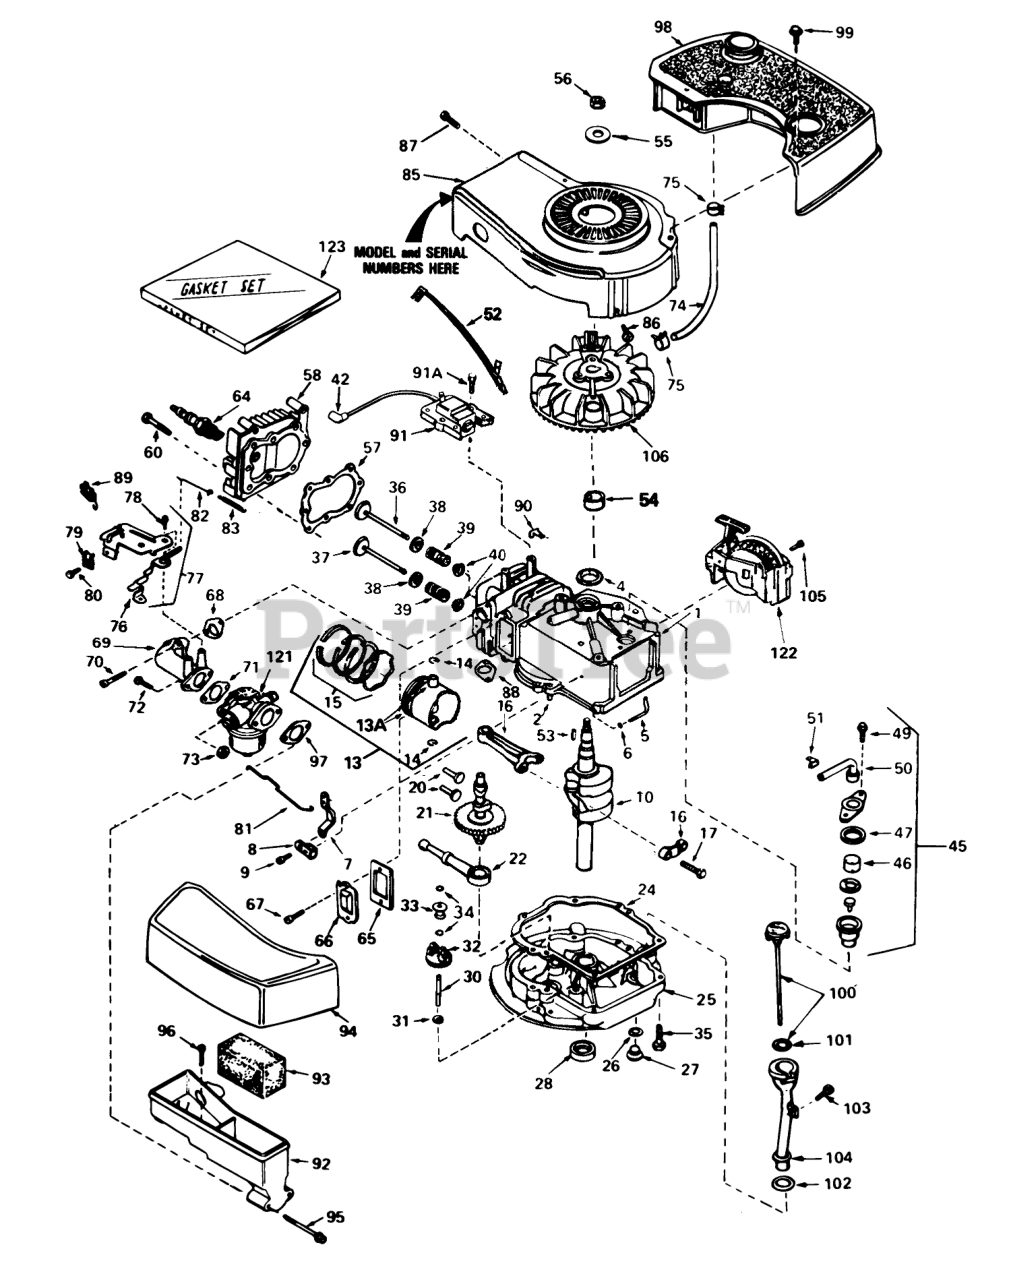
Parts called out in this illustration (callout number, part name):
1	Cylinder Assy. (Incl. #2 & 4)
2	Pin-Dowel
4	Seal-Oil
5	Rod, Governor (Incl. #6)
6	Washer-Flat
7	Governor Lever
8	Clamp-Lever, Governor
9	Screw
10	Crankshaft
13	Piston, Pin & Ring Assy. (Std.) (Incl. #13A, 14 & 15)
13	Piston, Pin & Ring Assy. (.010 oversize) (Incl. #13A, 14 & 15)
13	Piston, Pin & Ring Assy. (.020 oversize) (Incl. #13A, 14 & 15)
13A	Piston & Pin Assy. (Std.) (Incl. #14)
13A	Piston & Pin Assy. (.010 oversize) (Incl. #14)
13A	Piston & Pin Assy. (.020 oversize) (Incl. #14)
14	Ring-Retaining, Piston Pin
15	Ring Set (Std.)
15	Ring Set (.020" OS)
15	Ring Set (.010" OS)
16	Rod Assy., Connecting (Incl. #17)
17	Bolt-Rod, Connecting
20	Lifter-Valve
21	Camshaft(Mech.Comp. Release)
22	Oil Pump ASM
24	Gasket, Mounting
25	Flange Assy., Mounting (Incl. #26 thru 30)
26	Gasket-Oil Drain
27	Plug Oil Drain
28	Seal Oil
30	Shaft-Governor
31	Washer-Flat
32	Gear Assy., Governor (Incl. #31)
33	Spool-Governor
34	Ring-Retaining
35	Screw (1/4-20 x 1-1/4)
36	Valve, Intake (Std.) (Incl. #40)
36	Valve, Intake (1/32" oversize) (Incl. #40)
37	Valve, Exhaust (Std.) (Incl. #40)
37	Valve, Exhaust (1/32" oversize) (Incl. #40)
38	Cap-Upper Valve Spring
39	Spring-Valve
40	Cap-Valve, Spring
42	Cover-Spark Plug
45	Breather Assy. (Incl. #46 thru 51)
46	Element-Breather
47	Gasket-Breather
49	Screw (10-24 x 9/16)
50	Tube, Breaker
51	Clip, Breather
52	Wire-Ground
53	Key-Flywheel
55	Washer-Belleville
56	Nut-Flywheel
57	63573 GIL 42 SNWTHW
58	Head-Cylinder
60	Screw (5/16-18x1-1/2)
64	Plug, Spark (J17LM or equiv.)
64	Plug, Spark (Champion RCJ-8)
65	Gasket-Breather
66	Cover-Valve
68	Gasket-Intake
69	Pipe, Intake (Incl. #68)
70	Screw (1/4-20 x 1)
71	Gasket-Carburetor
72	Screw (1/4-28 x 7/8)
73	Nut and Lock Washer (1/4-28)
74	Line-Fuel
75	Clamp-Line, Fuel
76	Lever Control
77	Control Assy., Speed (Incl. #76, 78 & 89)
78	Screw, Hex Washer Hd Shoulder Self-Tap
79	Conduit
80	Screw (10-32 x 3/8)
81	Link-Throttle
82	Link Governor Spring
83	Spring Governor
85	Housing-Blower
86	Screw (1/4-20x19/32)
87	Screw (10-24 x 9/16)
88	Gasket Exhaust
89	Terminal
90	Clip-Wire
91	Lamination & Coil Assy. (Solid State) (Incl. #42)
91A	Screw
92	Body Air Cleaner
93	Filer, Air
94	Cove, Air Cleaner
95	Screw Fil Hd.
96	Screw, Hex Hd.
97	Gasket-Air Cleaner
98	Tank-Fuel
99	Screw (10-32 x 35/64)
100	Dipstick, Oil (Incl. #101)
103	Screw (10-32 x 1/2)
104	Tube-Oil Fill
105	Screw (1/2-20x5/8)
106	Flywheel
121	Carburetor (Incl. #71)
122	Starter-Sidemount
123	Gasket Set (Incl. items marked )
